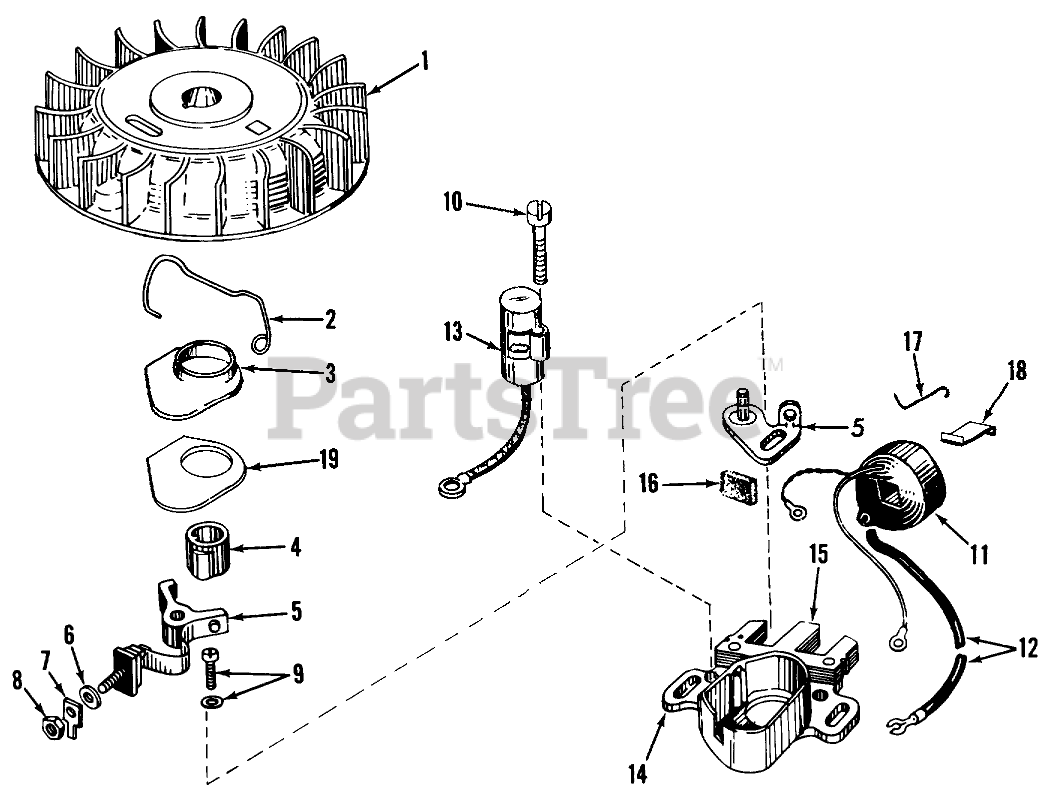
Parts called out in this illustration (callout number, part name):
1	Flywheel
2	Spring Breaker Box
3	Cover, Dust
4	Cam-Breaker
5	Breaker Assy.
7	Terminal
9	Breaker Screw
10	Condenser Screw
11	Coil Assy., (Incl. Ref. Nos. 12, 13 & 18)
12	Wire, Lead
13	Condenser
14	Core & Plate
15	Stator Assy., (Incl. Nos. 2, 3, 5 thru 14 & 16 thru 19)
16	Felt,Cam Wiper
17	Clip, Coil
18	Spring Coil Wedge
19	Gasket Dust
